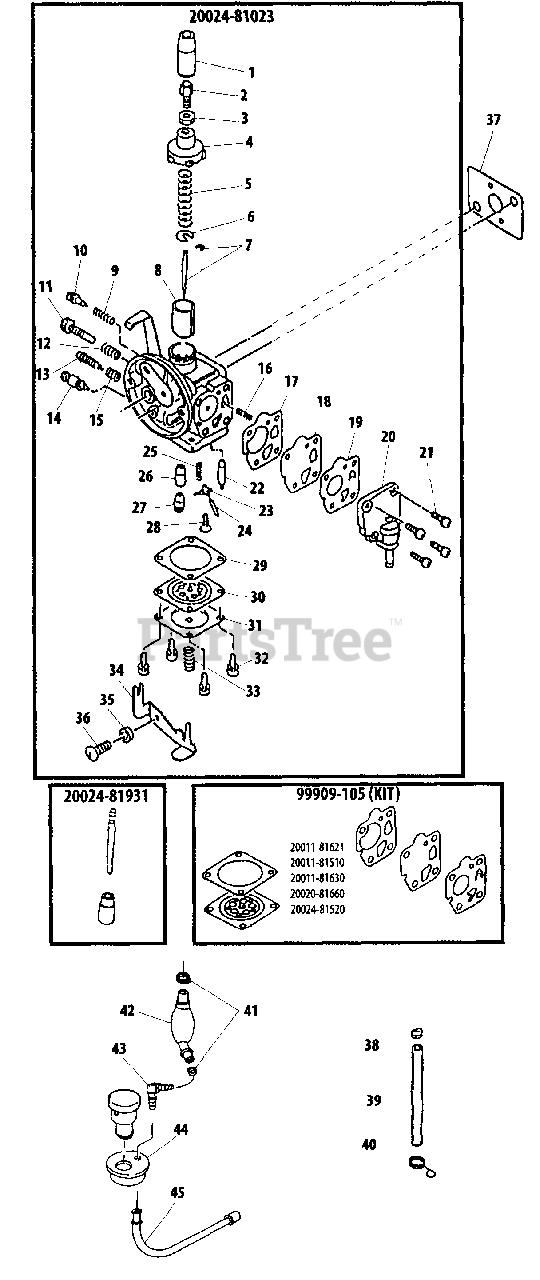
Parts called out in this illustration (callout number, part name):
1	GROMMET
2	ADJUSTER, CABLE
3	NUT, LOCK
4	CAP, CARBURETOR
5	SPRING
6	WASHER, SPRING SUPPORT
7	JET NEEDLE KIT
8	VALVE, THROTTLE
9	SPRING
10	SCREW, SLOW AIR
11	SCREW, IDLE ADJUST
12	SPRING
13	SCREW, MAIN ADJUST
14	VALVE, OVERFLOW
15	SPRING
16	SPRING
17	GASKET, DIAPHRAGM
18	DIAPHRAGM, METERING
19	VALVE, PUMP
20	BODY, PUMP
21	SCREW
22	VALVE, INLET NEEDLE
23	LEVER
24	PIN, METERING LEVER
25	SPRING
26	JET NEEDLE KIT
27	HOLDER, MAIN JET
28	SCREW M3×8
29	GASKET
30	DIAPHRAGM
31	COVER, DIAPHRAGM
32	SCREW M3×8
33	SPRING
34	LEVER, TICKLER
35	COLLAR
36	SCREW
37	GASKET, INTAKE
38	CLIP Ø6
39	PIPE, FUEL
40	HOLDER, PIPE
41	CLIP
42	PIPE, FUEL
43	CONNECTOR
44	GROMMET
45	PICK-UP TUBE
20024-81023	CARBURETOR
20024-81931	JET NEEDLE KIT
99909-105	DIAPHRAGM/GASKET KIT
